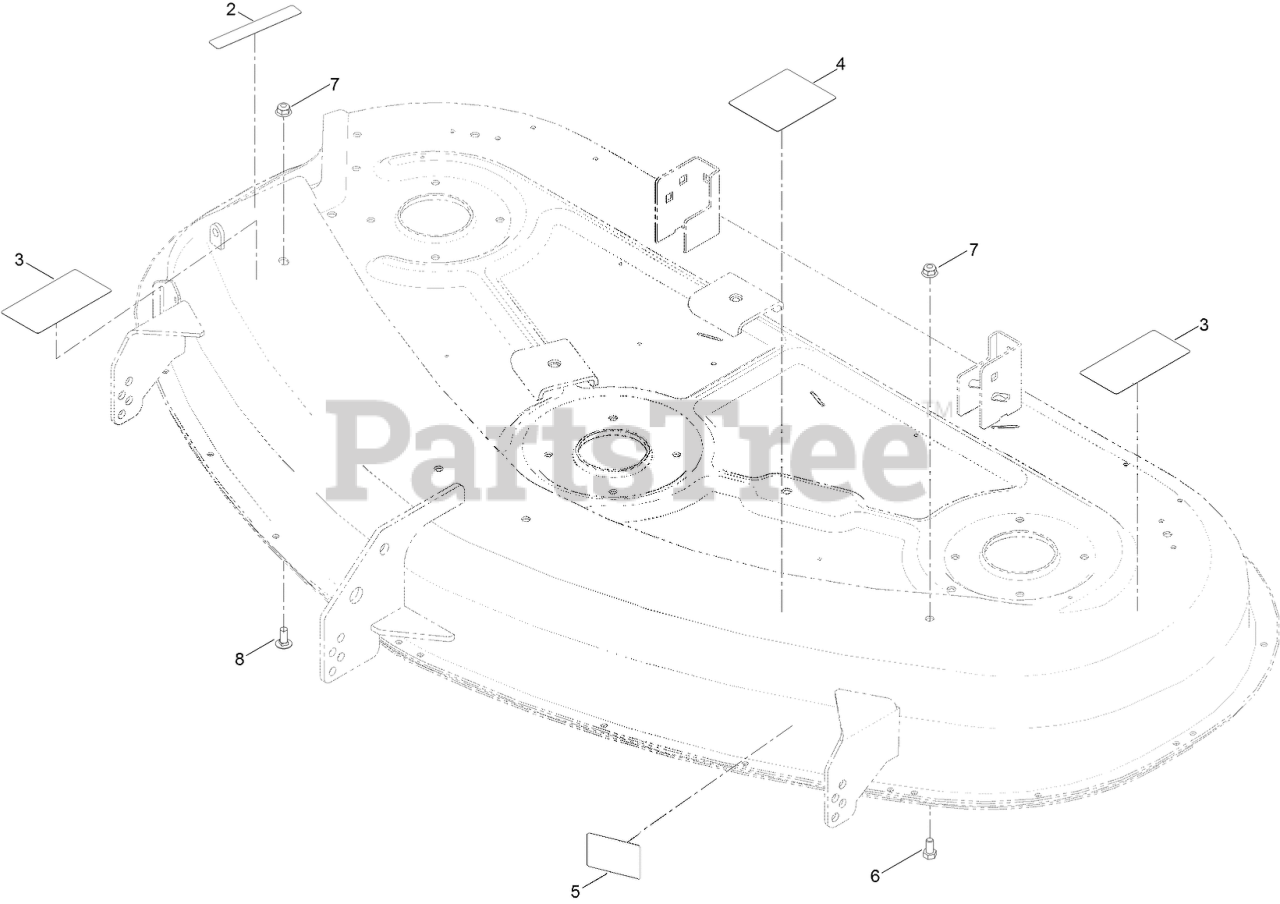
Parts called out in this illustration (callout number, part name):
2	DECAL-DANGER
3	DECAL-DANGER, DECK
4	DECAL-ROUTING, BELT
5	DECAL-SCALP, ANTI
6	SCREW-HH
7	NUT-HF, NI
8	SCREW-CARR
